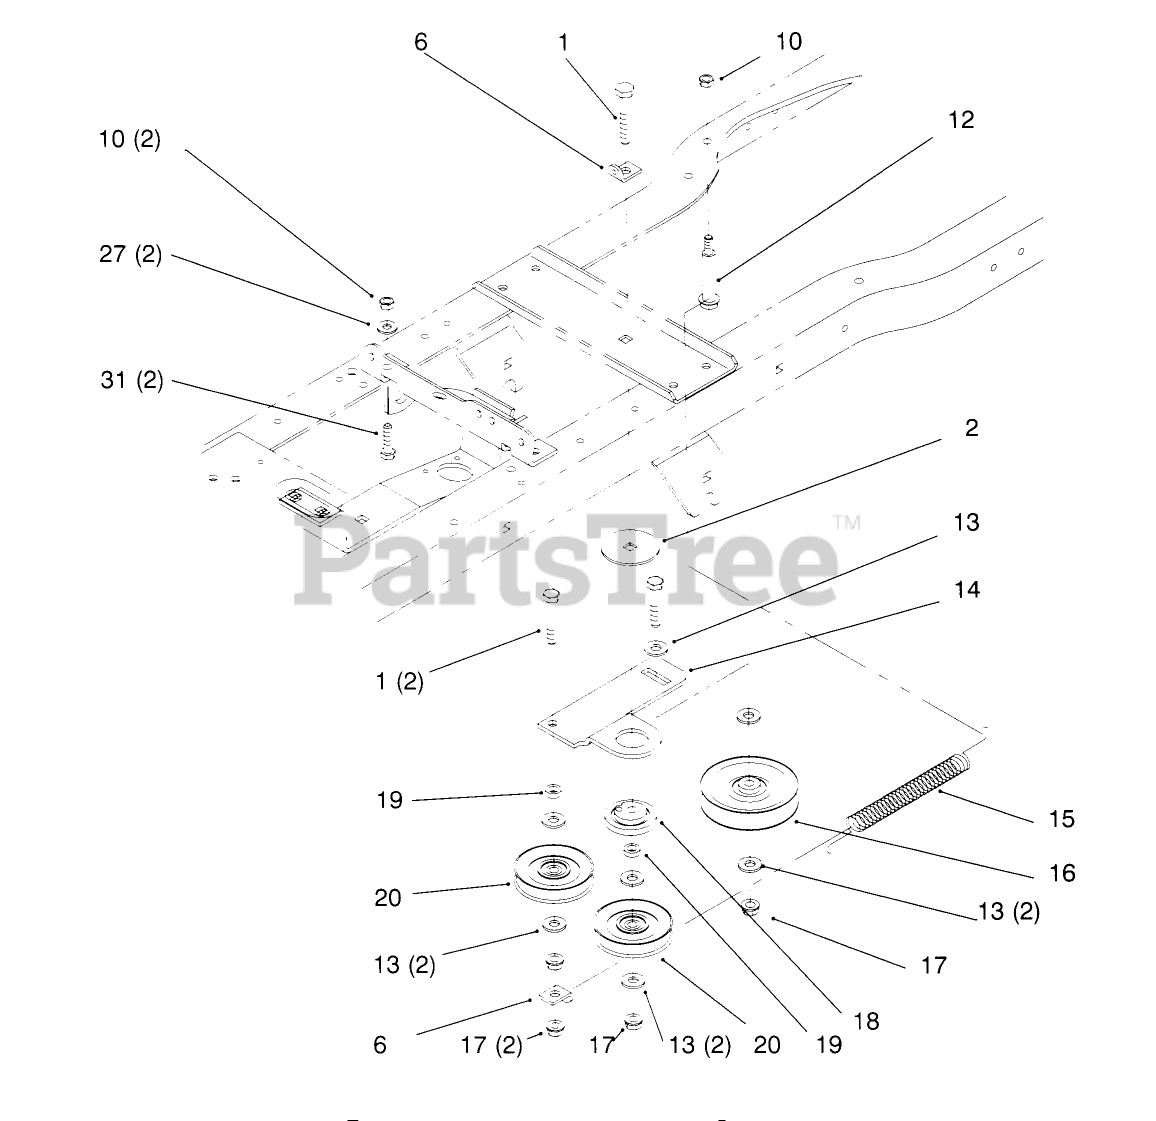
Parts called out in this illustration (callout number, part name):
1	SCREW-HH
2	WASHER-BEARING
6	CLIP - SPRING
10	NUT-LOCK, NI
12	BOLT-SHOULDER
13	WASHER-FLAT
14	ARM - IDLER
15	SPRING - CLUTCH
16	PULLEY-IDLER, FLAT
18	BUSHING
19	SPACER
20	PULLEY-IDLER
27	WASHER-PLAIN
31	SCREW-HH
